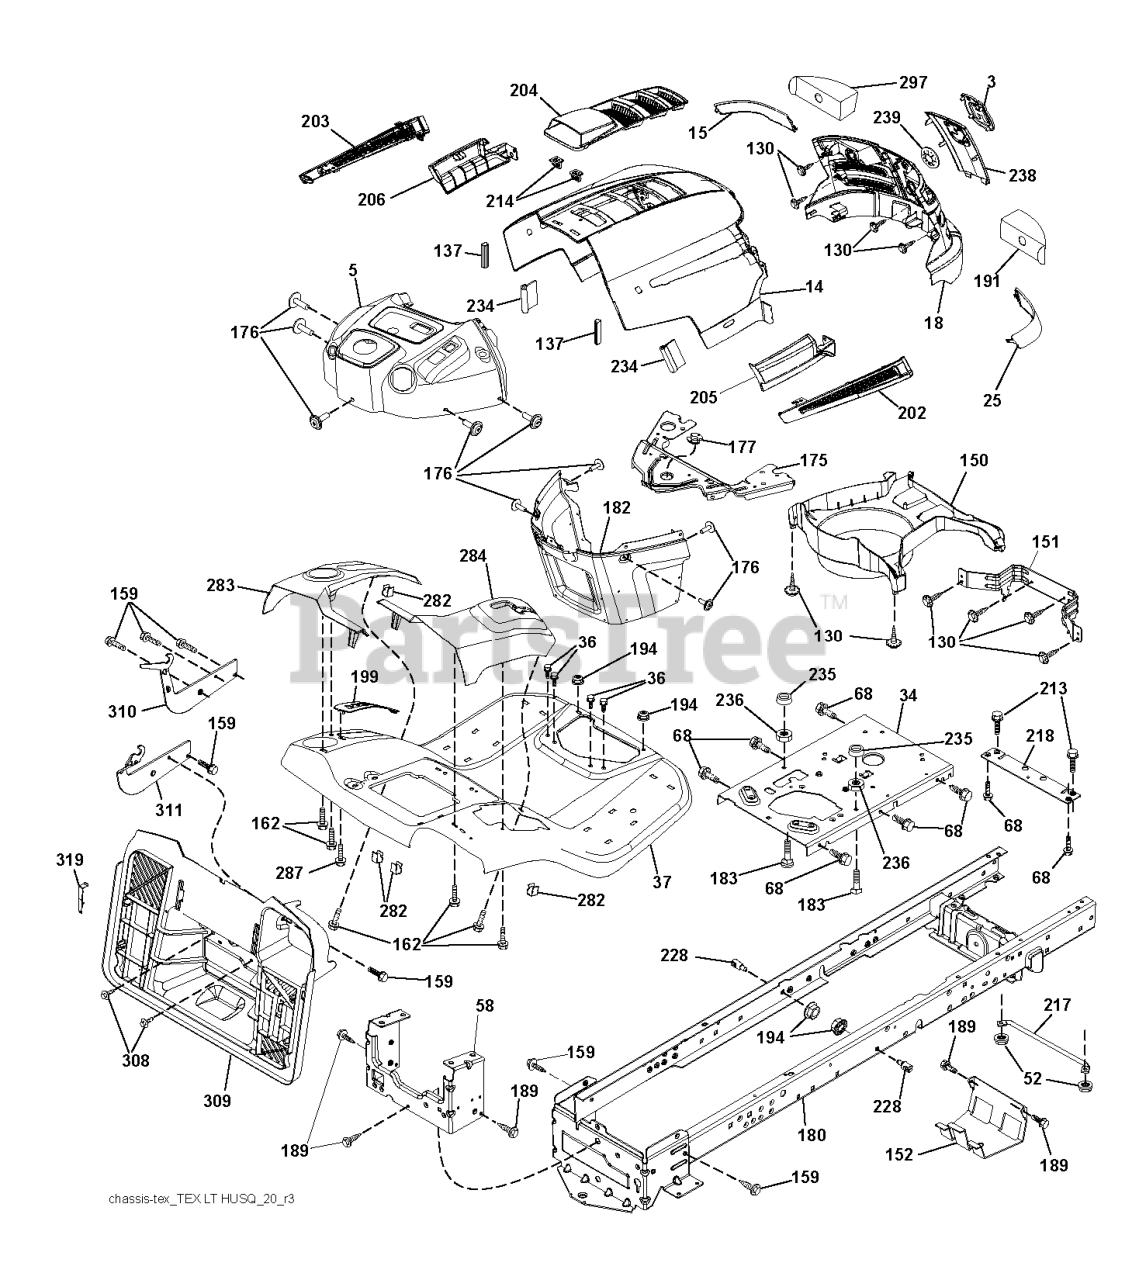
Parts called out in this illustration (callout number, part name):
3	RP LOGO
5	DASH
14	HOOD.HUSQVARNA.LT.ORANGE
15	LENS.HUSQVARNA LT.LH
18	GRILLE.SVC.HUSQVARNA.LT.GREY
25	LENS.HUSQVARNA LT.RH
34	PLATE.ENGINE.WELDED.CHASSIS
36	SCREW 5/16"
37	FENDER.TEX.SRD.CRD.BASE
52	LOCKNUT
58	DRAWBAR UPPER 2PC SMALL FENDER
68	Screw 5/16-18 x 1/2 Hex, Self Tapping 5/16-18 x 1/2
130	SCREW.#10 X 0.750.BOS
137	BUMPER DASH
151	BRACKET PIVOT
152	SHIELD.BROWNING.W/TEX
159	SCREW, 3/8-16X3/4
162	SCREW.HI-LO.CONSOLE
175	CROSSMEMBER
176	SCREW.#10-24X5/8.RN.QU
177	BUSHING STEERING
180	CHASSIS.WLDMNT.14GA.2PC.18".TI
182	DASH.LOWER.PREDATOR LT
183	BOLT.5/16-18X1-1/4 FULL THD
189	SCREW
191	INSERT.REFLECTIVE.RH.
194	NUT LOCK HEX FLANGE 5/16-18
199	PLATE DECK LIFT
202	VENT SIDE HOOD RH
203	VENT SIDE HOOD LH
204	VENT TOP HOOD
205	SKIRT SIDE RH
206	SKIRT SIDE LH
213	BOLT
214	CLIP.RETAINER.TINNER.
217	ROD.PIVOT.HOOD
218	X-PIECE.HOOD.STOP.NON/
228	STUD.FASTNER.W/ANTI-ROTATE
234	BUMPER.HOOD.TEX.HUSQVARNA
235	SPACER FENDER
236	NUT.CENTERLOCK.5/16-
238	TRIM
282	CLIP.RETAINER.CONSOLE.LT.HUSQ
283	CONSL.DECKLIFT.LH.SRD.TEX.CRD
284	CONSL.SHIFT.GEAR.RH.SRD.GREY
287	SCREW 1/4X20
297	INSERT REFLECTIVE
308	BOLT.5/16-18UNCX3/4 W/SEMS.BLK
309	BACKPLATE.BAGGER.V2.SRD
310	LH.ADJUST.HANGER.BRACKET.ASM
311	RH.ADJUST.HANGER.BRACKET.ASM
319	BRACKET.ACTUATOR.BAGGER.SRD
